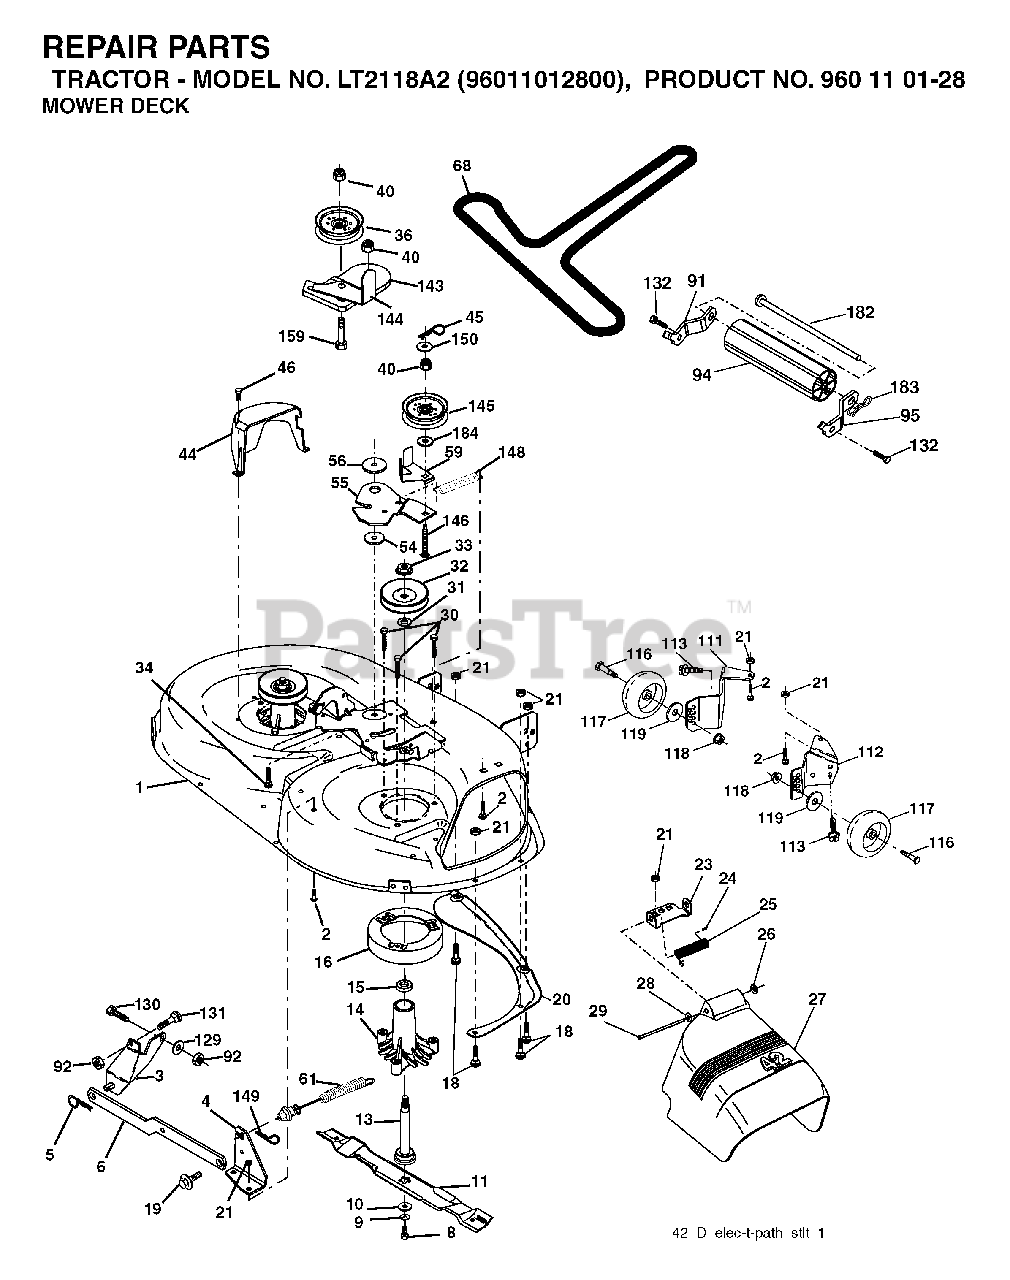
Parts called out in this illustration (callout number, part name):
1	42" DECK KIT
2	BOLT
3	BRKT ASM SWAY BAR
4	BRACKET SWAY BAR 42" DECK
5	RETAINER-SPRNG RB
6	BAR SWAY DECK
8	BLADE BOLT
9	LOCKWASHER
10	WASHER.BLADE
11	42" HI-LIFT BLADE
13	SHAFT ASM VENT
14	HSG MANDREL
16	STRIPPER, MWR ROUND
18	BOLT
19	BOLT SHD 5/16-18
20	BAFFLE.VORTEX
21	LOCKNUT
23	BRKT, DEFL. MOWER
24	CAP-SLEEVE LT
25	SPRING TORSION
26	NUT PUSH M
27	SHIELD DEFLECTOR
28	WASHER
29	ROD.HINGE
30	SCREW, WASHER HEAD
31	WASHER.SPACER.MANDREL
32	PULLEY/MANDREL
33	NUT.FLANGE.LOCK.TOP
34	BOLT.3/8-16X1.50
36	FLAT IDLER PULLEY
40	NUT LOCK FLG 3/8-16 UNC
44	GUARD MANDREL LH BLACK
45	RETAINER M
46	SCREW.1/4-20X5/8
55	ARM IDLER 42" MOWER LT/YT
56	SPACER.RETAINER.MOWER
59	GUARD, BELT
61	SPRING EXT ELEC CLUTCH
91	BRACKET ASM NOSEROLLER LH
92	NUT
94	NOSE ROLLER
95	BRACKET ASM NOSEROLLER RH
111	BRACKET, WHEEL
112	BRACKET, WHEEL
113	BOLT.5/16HEX.WHS.HD
117	WHEEL.GAGE.HALF.SPOKED
118	LOCKNUT
119	WASHER
129	WASHER
131	BOLT D
132	SCREW, 3/8-16X3/4
143	BRACKET, ARM IDLER
144	KEEPER.BELT.42".CLUTCH.CABLE
145	PULLEY
146	BOLT, CARRIAGE IDLER BLACK
148	IDLER RETURN SPRING
149	SPRING.RETAINER.YELLOW.ZINC
150	WASHER LT
159	BOLT
182	ROD ROLLER NOSE STANDARD
183	PIN.COTTER.7/16.BOW TI
184	WASHER
